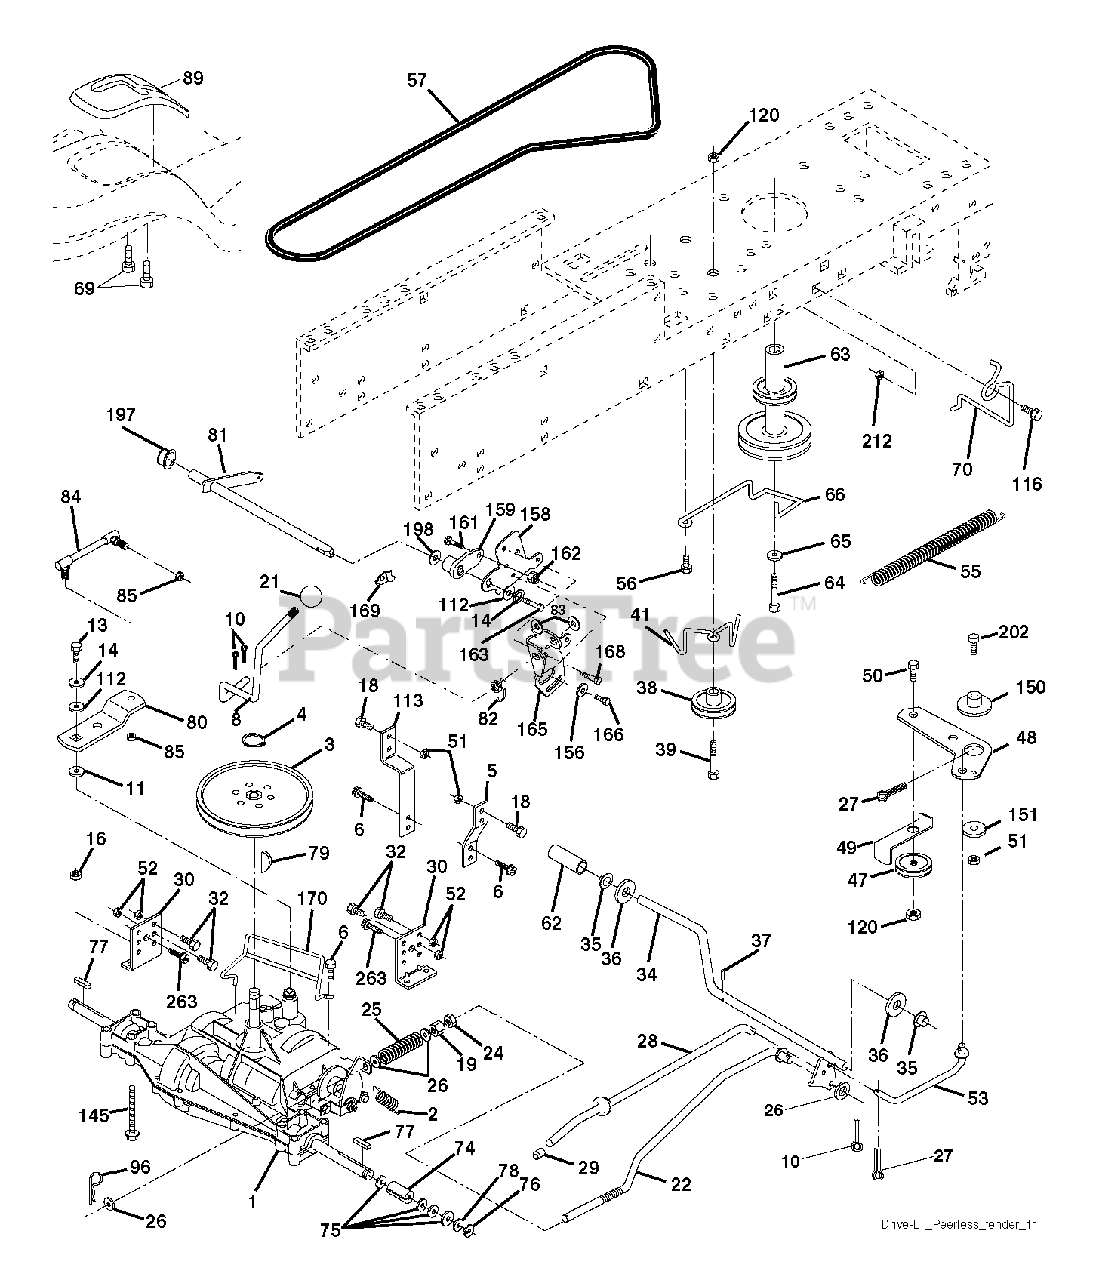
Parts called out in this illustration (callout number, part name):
2	SPRING,BRAKE RETURN
3	PULLEY TRANS
4	RETAINING RING LT
5	STRAP TORQUE
6	SCREW 5/16"
8	ROD SHIFT FENDER ADJUST LT
10	PIN COTTER
11	WASH-SHFT PLT LT
13	Bolt, 1/4-20 unf Grade 8 w/Patch
14	LOCKWASHER
16	NUT.71038.31-18.HEX.NYLOCK
19	NUT
21	KNOB T (1/2-HOLE)
22	ROD BRAKE
24	NUT
25	SPRING ROD LT
27	COTTER PIN
28	ROD, PARKING BRAKE
29	PLUNGER CAP
30	BRKT, TRNSXLE MNT 20"
32	BOLT
34	SHAFT, FOOT PEDAL
35	BEARING.NYLON
36	WASHER LT
38	PULLEY IDLER COMPOSITE
41	KEEPER, BELT IDLER
47	Idler Pulley
48	BELLCRANK, CLUTCH
49	RETAIN BELT
50	BOLT.3/8-16X1.50
51	LOCKNUT
52	LOCKNUT
53	LINK.CLUTCH.7.66.2005
55	SPRING, RETURN LT
56	SCREW.3/8-16
57	BELT, V GROUND DRIVE 95 25
63	ENGINE PULLEY
64	BOLT HEX 7/16-20X4-1/4"
65	LOCKWASHER
66	KEEPER BELT ENGINE
69	SCREW.HI-LO.CONSOLE
70	KEEPER BELT ENG
74	SPACER AXLE
76	E-RING LT
77	SQUARE KEY
79	KEY STD (1373) DANA
80	ARM SHIFT
81	SHAFT ASM CROSS TAPERED PMST/2
82	SHIFT SPRING
83	WASHER
84	LINK.TRANSAXLE.PMST/DANA.20"
85	NUT LOCK CENTER 1/4 -28 FNTHD
89	CONSOLE SHIFT STLT
112	WASHER LT
113	STRAP TORQUE LH LT
120	NUT LOCK FLG 3/8-16 UNC
150	SPACER, RETAINER
151	WASHER 12/32X2X10GA
156	WASHER.SRRTD.5/16
158	BRACKET.SHIFT.MOUNT
159	HUB.SHIFT
161	BOLT
162	NUT.CROWNLOCK.1/4
165	BRACKET.PIVOT.LEVER
168	BOLT.SHOULDER.5/16-18X
169	PLATE.FASTENING.CROSS.SHAFT
170	KEEPER BELT T/A
197	NYLINER SNAP 5/8" ID
198	WASHER.NYL.7/8IDX.105"HYD CR
202	BOLT
212	NUT LOCK FLG 3/8-16 UNC
263	SCREW, 3/8-16X3/4
